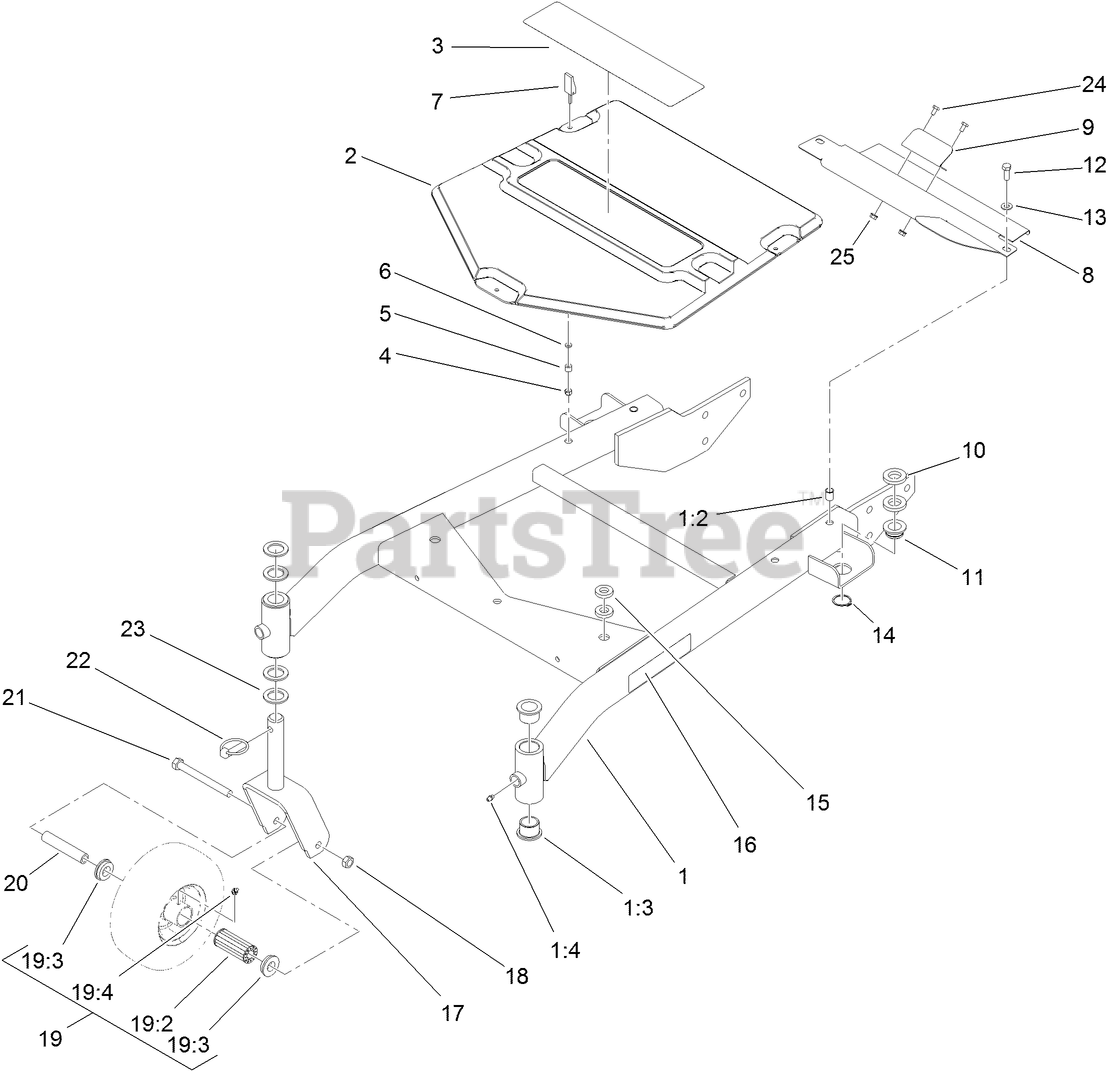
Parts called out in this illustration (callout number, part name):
1	CARRIER FRAME ASM
1:2	INSERT-NUT
1:3	BUSHING
1:4	FITTING-GREASE
2	COVER-FRAME, CARRIER
4	NUT-LOCK, HH
5	BUSHING-LATCH, SWELL
6	WASHER
7	HANDLE-LATCH, SWELL
8	SHIELD-BELT
9	SHIELD-HEAT, MANIFOLD
10	SPACER-SUPPORT, DECK
11	BUSHING-DECK
12	SCREW-HH
13	WASHER-FLAT
14	RING-RETAINING
15	SPACER
17	FORK-CASTOR
18	NUT-HEX
19	WHEEL AND TIRE ASM
19:2	BEARING-ROLLER
19:3	BUSHING
19:4	FITTING-GREASE
20	BUSHING-SPANNER
21	SCREW-HH
22	PIN-LYNCH
23	WASHER-THRUST
24	SCREW-HH
25	NUT-HHF
